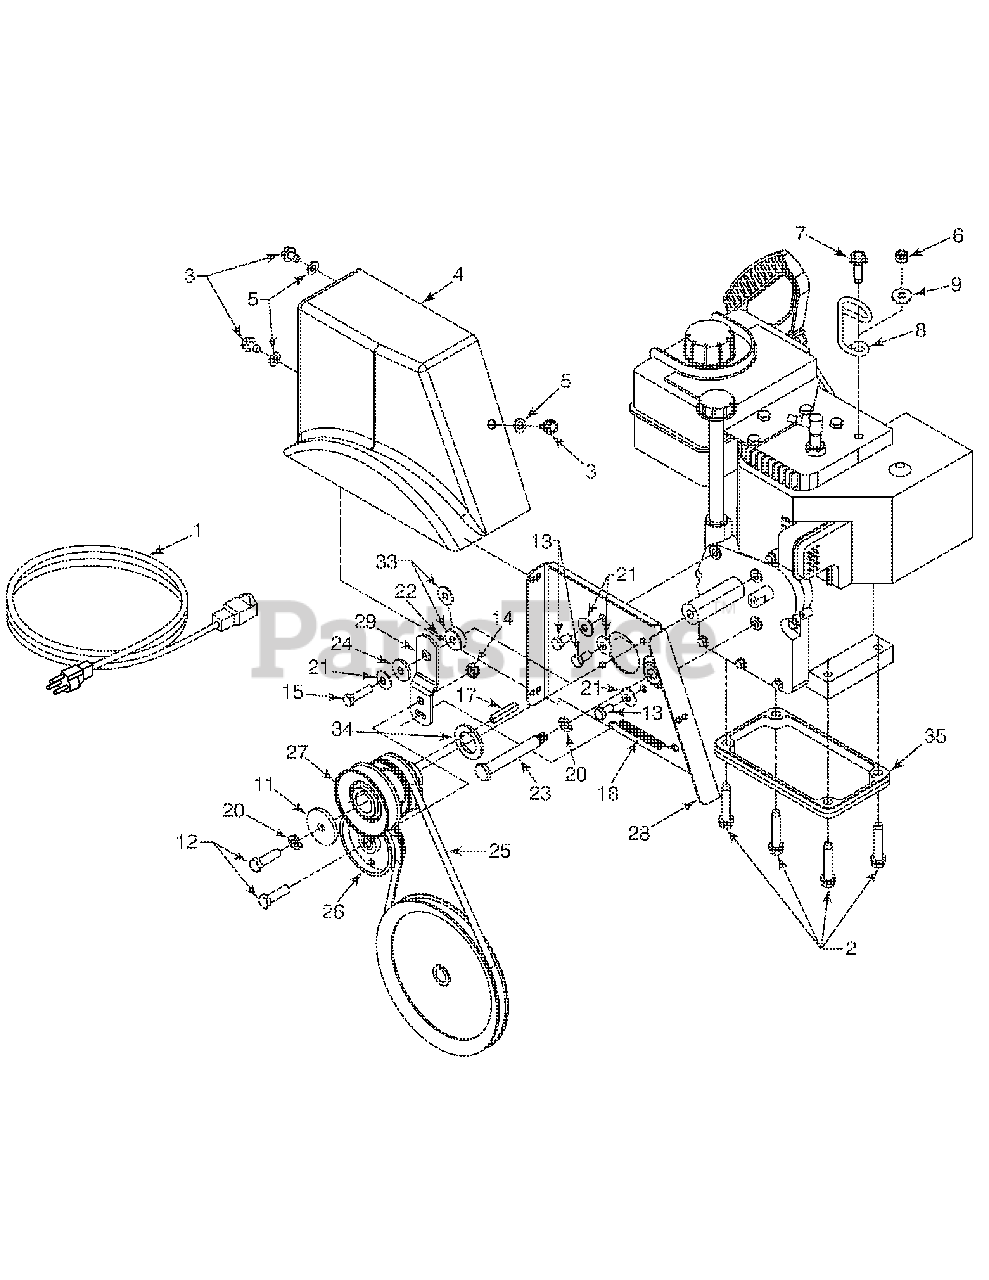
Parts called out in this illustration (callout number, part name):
1	Extension Cord 10 Ft.
2	Hex L-Wash TT Scr. 3/8-16 x 1.8 (for 10 & 11 HP)
3	Hex Wash HD S-Tapp Scr 5/16-18 x .50
4	Plastic Belt Cover
5	Flat Washer .330 ID x .630 OD x .0635
6	Hex Flg. L-Nut 1/4-20 Gr. F Nylon
7	Hex Wash Hd Tapp Scr 5/16-18 x 1.00
8	Cable Control Wire
9	Flat Washer .28 ID x .74 OD x .063
11	Flat Washer .450 ID x 1.250 OD x .164
12	Hex Screw 3/8-24 x 1.25 Gr. 8 Special
13	Hex Screw 5/16-24 x .625 Gr. 5
14	Hex Nut 3/8-24 Gr. 5 Nylon
15	Hex HD. Cap Scr. 5/16-24 x 1.25 Lg. Gr 5 (for 10 & 11 HP)
17	Square Key 1/4 x 1/4 x 1.50" Lg.
18	Brake Return Ext. Spring 3.18" Lg.
20	Lockwasher Heavy 3/8" ID
21	Cupped Washer .340 ID x .872 OD x .06
22	Grease Arctic
23	Shoulder Screw .498 x 3.245 x 3/8-16 (for 10 & 11 HP)
24	Shoulder Spacer .25 THK
25	V-Belt 3/8 x 35.5" Lg.
26	Flat Idler w/flanges 3.0 OD
27	Double Groove Engine Pulley
33	Spacer .33 ID x 1.01 OD x .36 (for 10 & 11 HP)
34	Spacer 1.02 x 1.63 x .1425 (for 10 & 11 HP)
35	Engine Spacer .560 Thick (for 10 & 11 HP)
